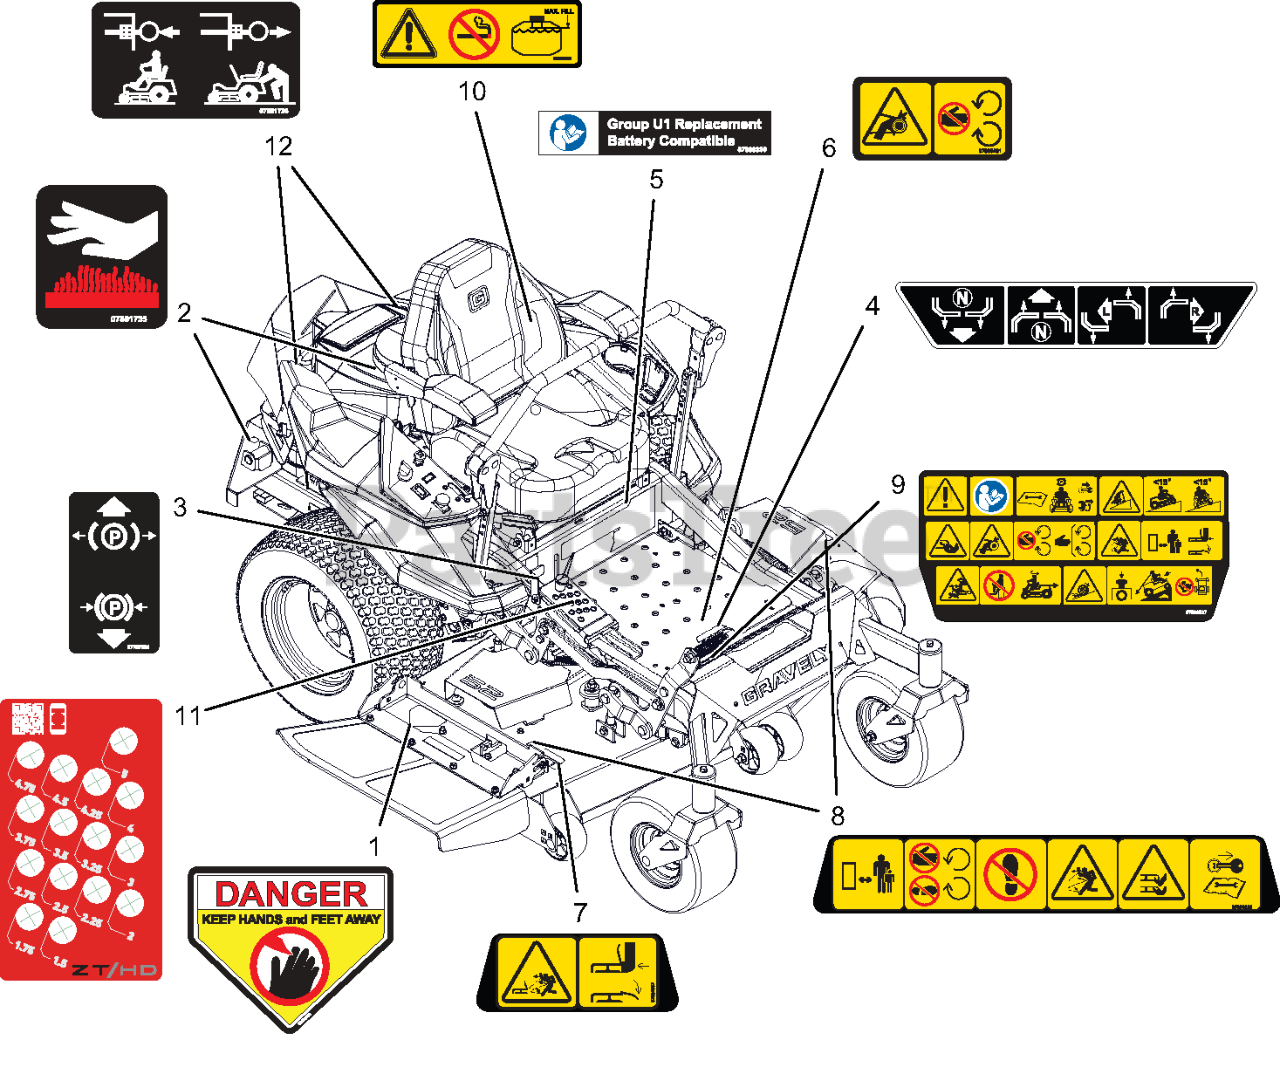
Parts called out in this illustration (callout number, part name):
1	DECAL, DANGER
2	DECAL,SAFETY HOT SURFACE
3	DECAL, PARKING BRAKE LEVER
4	DECAL- INSTRUCTIONAL-STEERING
5	DECAL, U1 BATTERY REPLACEMENT
6	DECAL, SAFETY - GUARDING
7	DECAL- SAFETY - DECK GUARDING
8	DECAL- SAFETY - MOWER DECK
9	DECAL, MAIN SAFETY
10	DECAL, FUEL WARNING
11	DECAL, ZT HD HOC
12	DECAL,TRANSAXLE DISCONNECT
